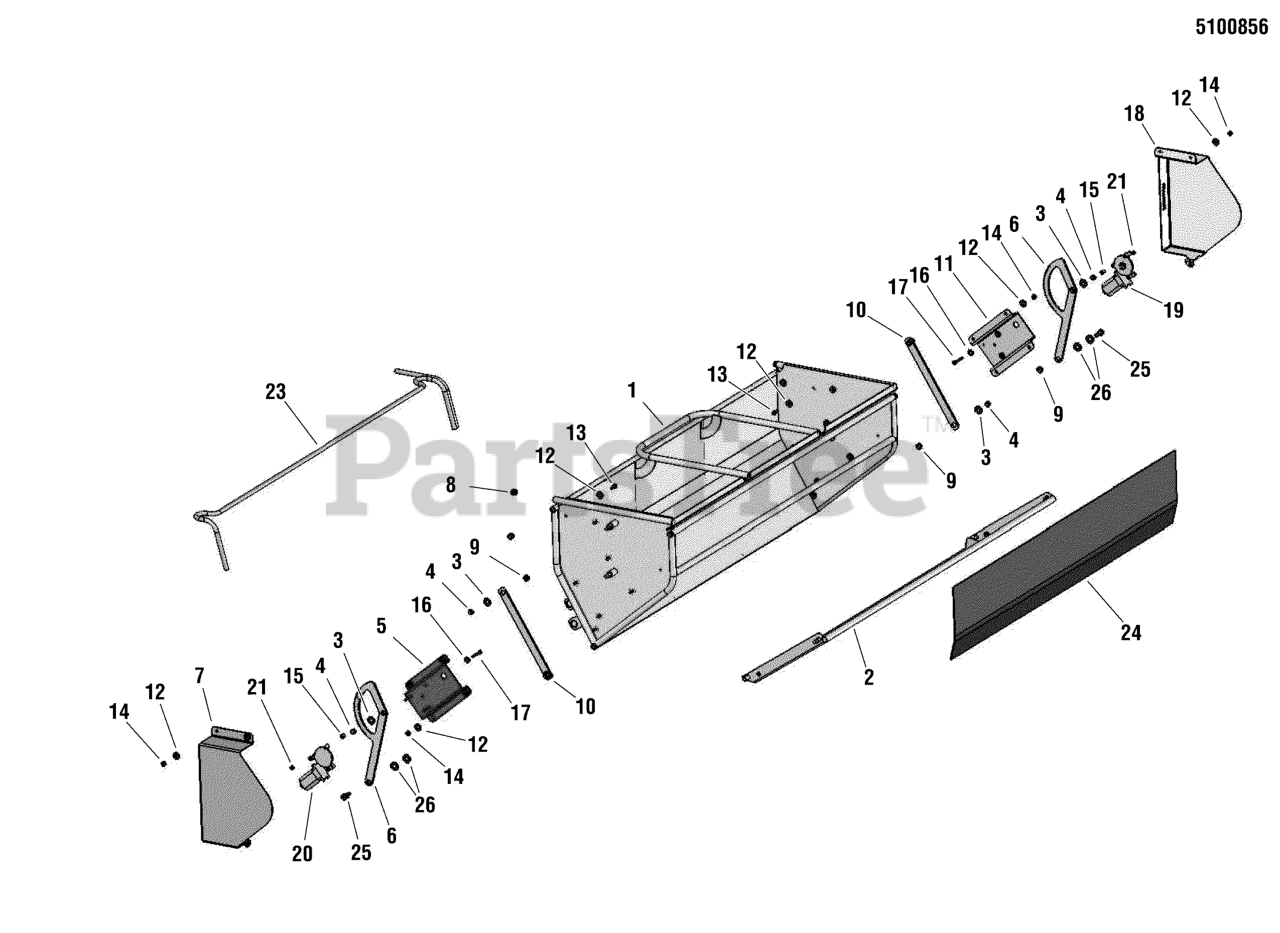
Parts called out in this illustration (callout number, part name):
1	DUMP FRAME (HUMBOLDT)
2	GATE ASSEMBLY (HUMBOLDT)
3	WASHER, 3/8 SAE
4	NUT, 3/8-16 HEX NYLON LOCK
5	MOTOR ADAPTER PLATE, FRA150573
6	DFS ELEC DRIVE RING-GREAR, FRA150568
7	DFS MOTOR GUARD, LEFT, FRA150571
8	3/4" HOLE PLUG, PLASTIC (HUMBOLDT)
9	FLANGE BUSHING, FAS150945
10	MASTER LINK, FRA150569
11	MOTOR ADAPTER PLATE, FRA150574
12	WASHER, 5/16 GD.9 FLAT
13	CAP SCREW 5/16-18 X .75, FRA150799
14	NUT, 5/16-18 HEX NYLON LOCK
15	MOTOR OFFSET BOSS, FRA150575
16	WASHER, 1/4 FENDER
17	CAP SCREW 1/4-20 X 1 3/4, FRA150939
18	DFS MOTOR GUARD, RIGHT, FRA150572
19	ELECTRIC MOTOR, RIGHT HAND, FRA150549
20	ELECTRIC MOTOR, LEFT HAND, FRA150548
21	NUT, 1/4-20 HEX NYLON LOCK
22	DFS IMPLEMENT WIRING HARNESS, FRA150721
23	DFS 3-BAG WIRING HARNESS, FRA150723
24	3 BAG DFS FABRIC, 305 012 011
25	SHOULDER BOLT, FAS150947
26	WASHER, 1/2 SAE
